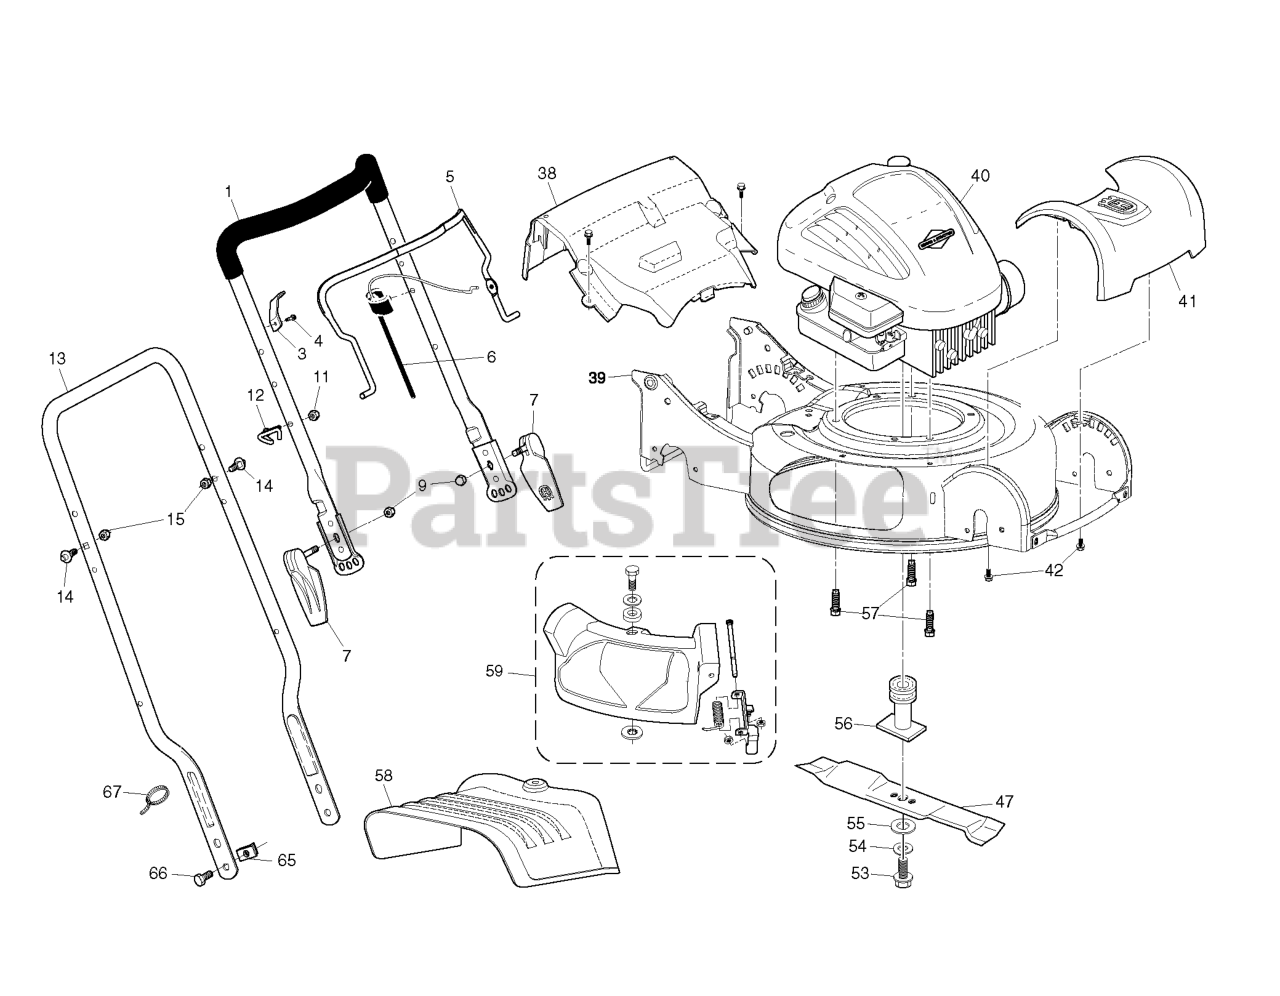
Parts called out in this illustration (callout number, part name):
3	BRACKET.UPSTOP.RT
5	BAIL.CONTROL.MZR.BS.ORANGE
6	CONTROL.ZONE.ASM
7	QUICK.ASM.RELEASE.BLACK
9	Locknut, Hex 1/4-20
11	NUT
12	RB GUIDE.ROPE.STD.BLK.ZIN WSL
14	STUD.QUICK.ADJUST
15	NUT.LOCK.5/16-18
42	SCREW.HWH.13-16-5.8.BZP
53	BOLT.HD.HEAD.3/8-24X2.50 (2 2)
54	LOCKWASHER
55	WASHER,HARDEN
57	BOLT 3/8-16X1-1/8
67	TIE GUIDE
